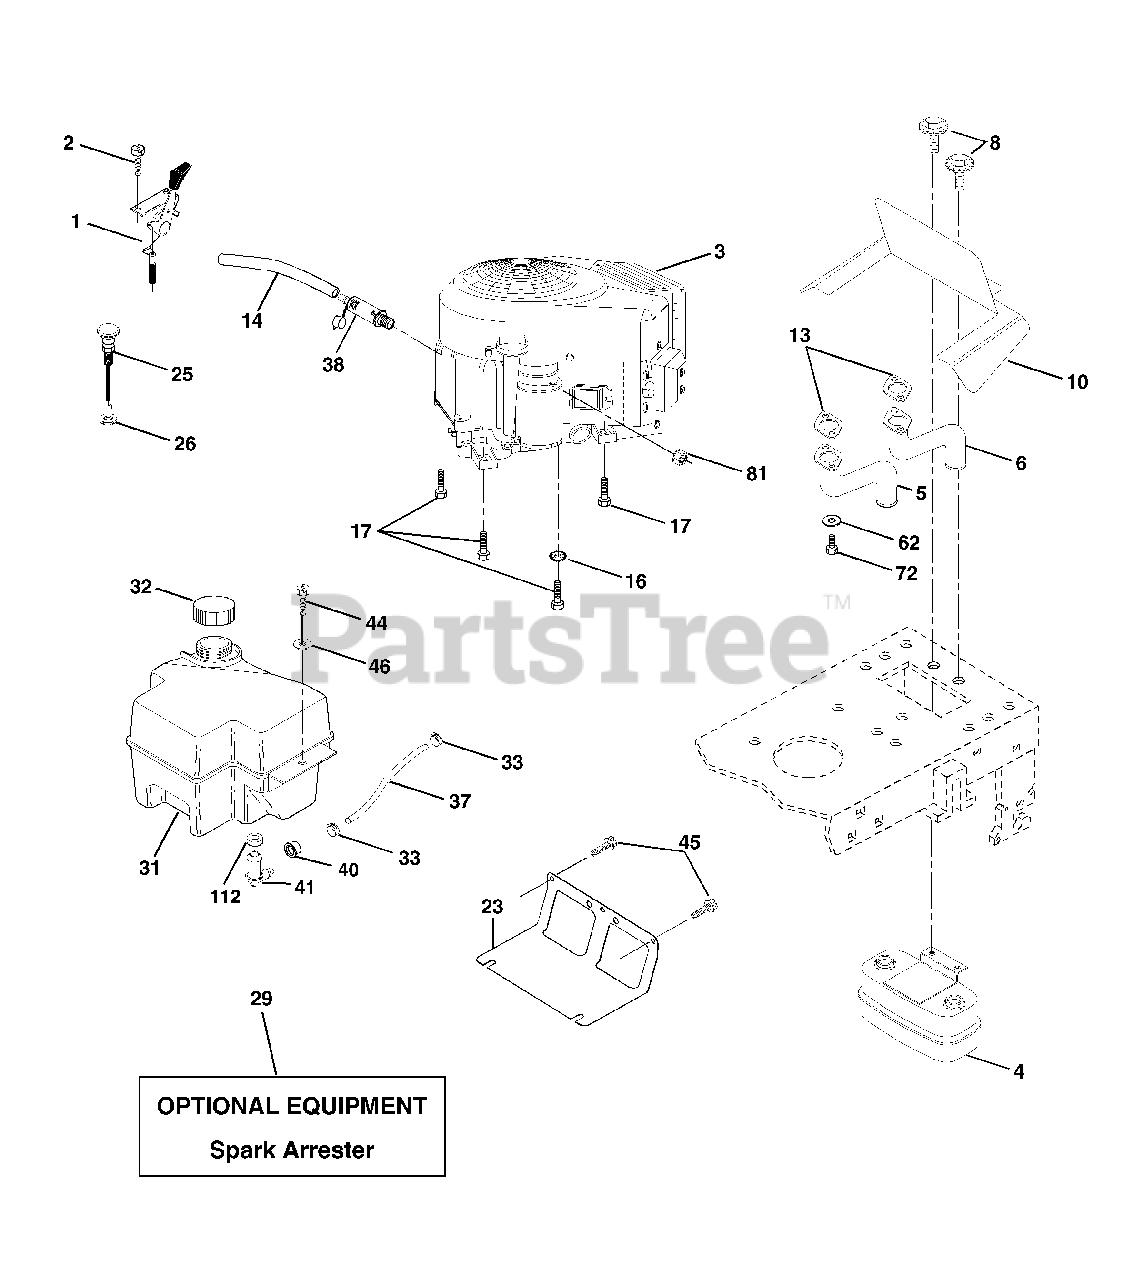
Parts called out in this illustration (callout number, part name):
1	Control, Throttle
2	Screw Hex Thd Cut 1/4-20 x 1/2
4	Muffler, Asm. Twin Lo-Tone
5	Pipe Exhaust Intek 20 RH
6	Pipe Exhaust Intek 20 LH
8	Bolt 5/16-18 UNC x 3/4 w/Sems
10	Shield Browing B&S Intek II
13	Muffler Gasket
14	Tube Drain Oil Easy
16	Washer, Lock Ext tooth 3/8
17	Screw 3/8-16 x 1-1/2
23	Shield, Browning/Debris Guard
25	Control Choke
26	Nut Keps 3/8-24 UNF
29	Arrester, Spark
31	Tank, Fuel
32	Cap Gauge, Fuel
33	Clamp, Hose Blk
37	Line, Fuel 7.5
38	Plug Drain Oil Easy
40	Bushing Snap Nyl Blk Fuel Line
41	Stem Tank Fuel
44	Screw Hex Wsh Thdrol 1/4-20 x 3/4
45	Screw Hex Wsh Thdrol 3/8-16 x 3/4
46	Washer 9/32 x 7/8 x 16 Ga.
62	Washer Lock Hvy Hlcl Spr 5/16
72	Screw Hex Hd Cap 5/16-18 x 3/4
81	Nut Keps Hex 1/4-20 Unc
112	Bushing
